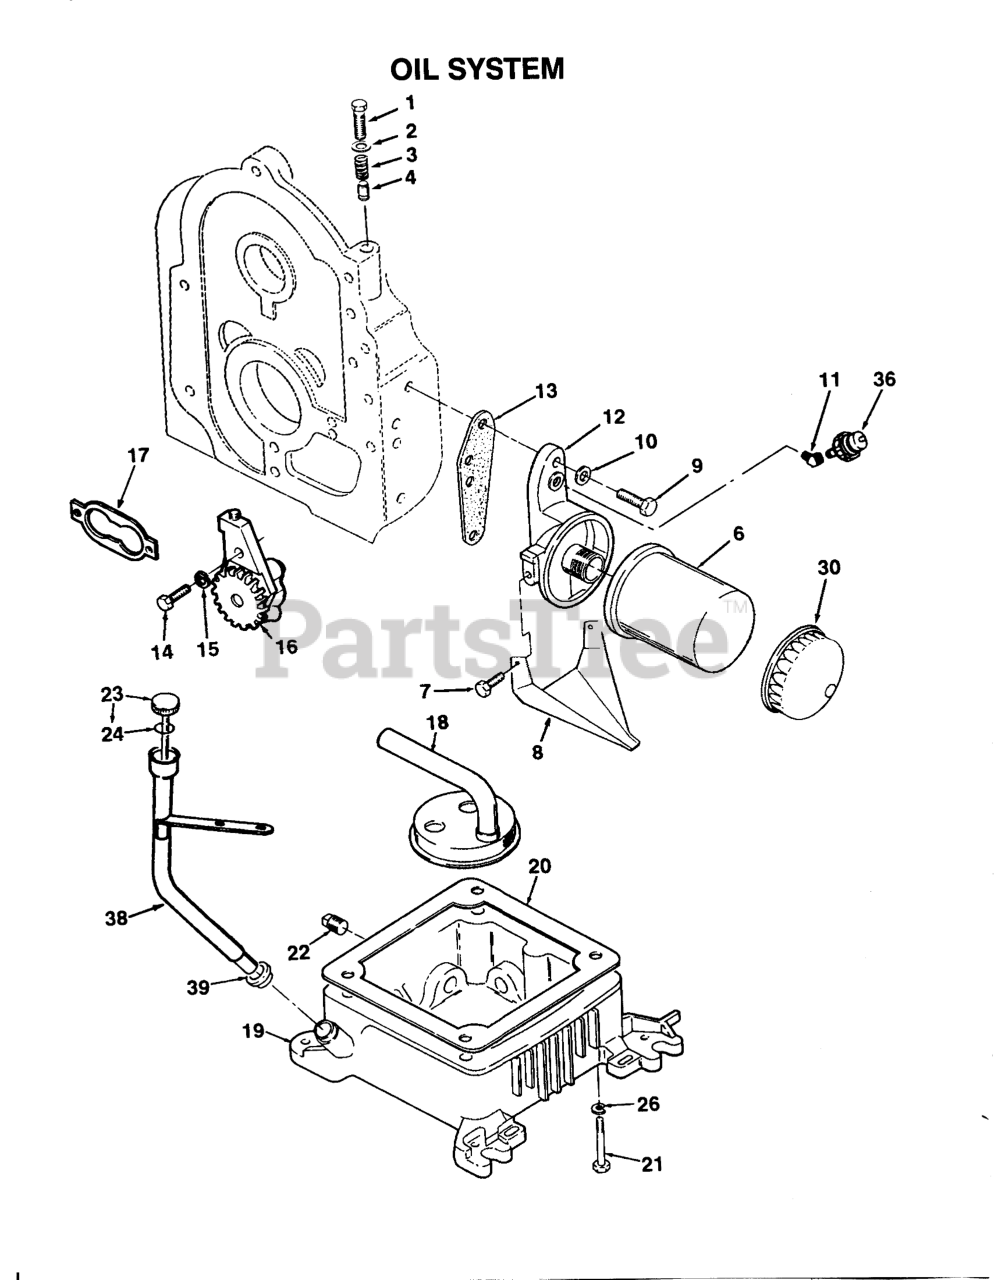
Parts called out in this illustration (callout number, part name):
1	HX HD CAPSCREW
2	WASHER
3	SPRING
4	PLUNGER
6	FILTER-OIL
7	SCREW-HH
8	DRAIN-OIL FILTER
9	HHCS 5/16-18 X 1
10	WASHER
11	ELBOW-45 DEG
12	ADAPTER-OIL FILTER
13	Gasket
14	SCREW - CAP HEX HEAD
15	WASHER-FLAT
17	GASKET KIT
18	CUP-OIL PUMP INTAKE
19	Base-Oil (Incl. Plugs)
20	GASKET
21	Screw
23	Oil Fill Cap & Indicator (Incl. O-Ring)
24	SEAL 0-RING
26	WASHER-FLAT
30	WRENCH-OIL FILTER
36	OIL-PRESSURE SWITCH
38	TUBE-OIL FILTER
39	SEAL-OIL FILL TUBE
